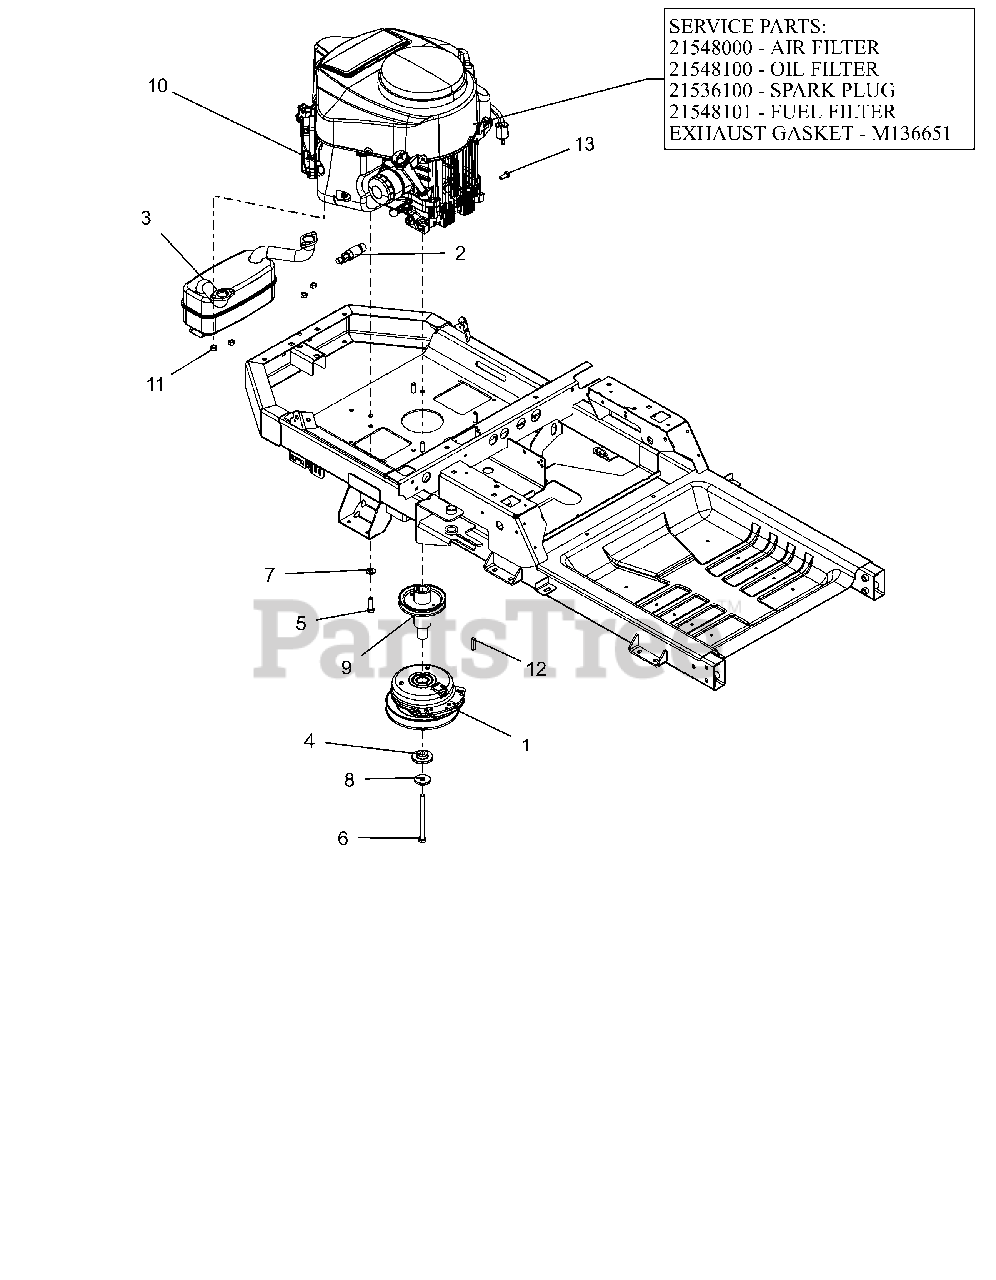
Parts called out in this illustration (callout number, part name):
1	CLUTCH,105FTLB MONOPOLE 6.83"
2	DRAIN, OIL M20X2.5
3	MUFFLER, KAWASAKI
4	BSHG-FLG .469X1.06X.574X2.0
5	BLT-HEX.38-16X1.25 G5YZ NYTORQ
6	BLT-HEX.438-20X5 GR8 YZ NYTORQ
7	WASHER, 3/8" SPRING DISC
8	WASHER, 7/16" SPRING DISK
9	WLDMT, DRIVE SHEAVE (LG XL)CZC
10	ENGINE, KAWASAKI FR691 23HP
10	AIR FILTER, KAWASAKI FR
10	OIL FILTER, KAWASAKI FR
10	PLUG, SPARK
10	FUEL FILTER-KAWASAKI FR
10	GASKET, MUFFLER #
11	NUT-LK-TOP M8-1.25 YWZC
12	KEY-SQ .25 X 1.25 X .25 SAE
13	BLT, HEX M8-1.25X20 G8.8 ZCC
